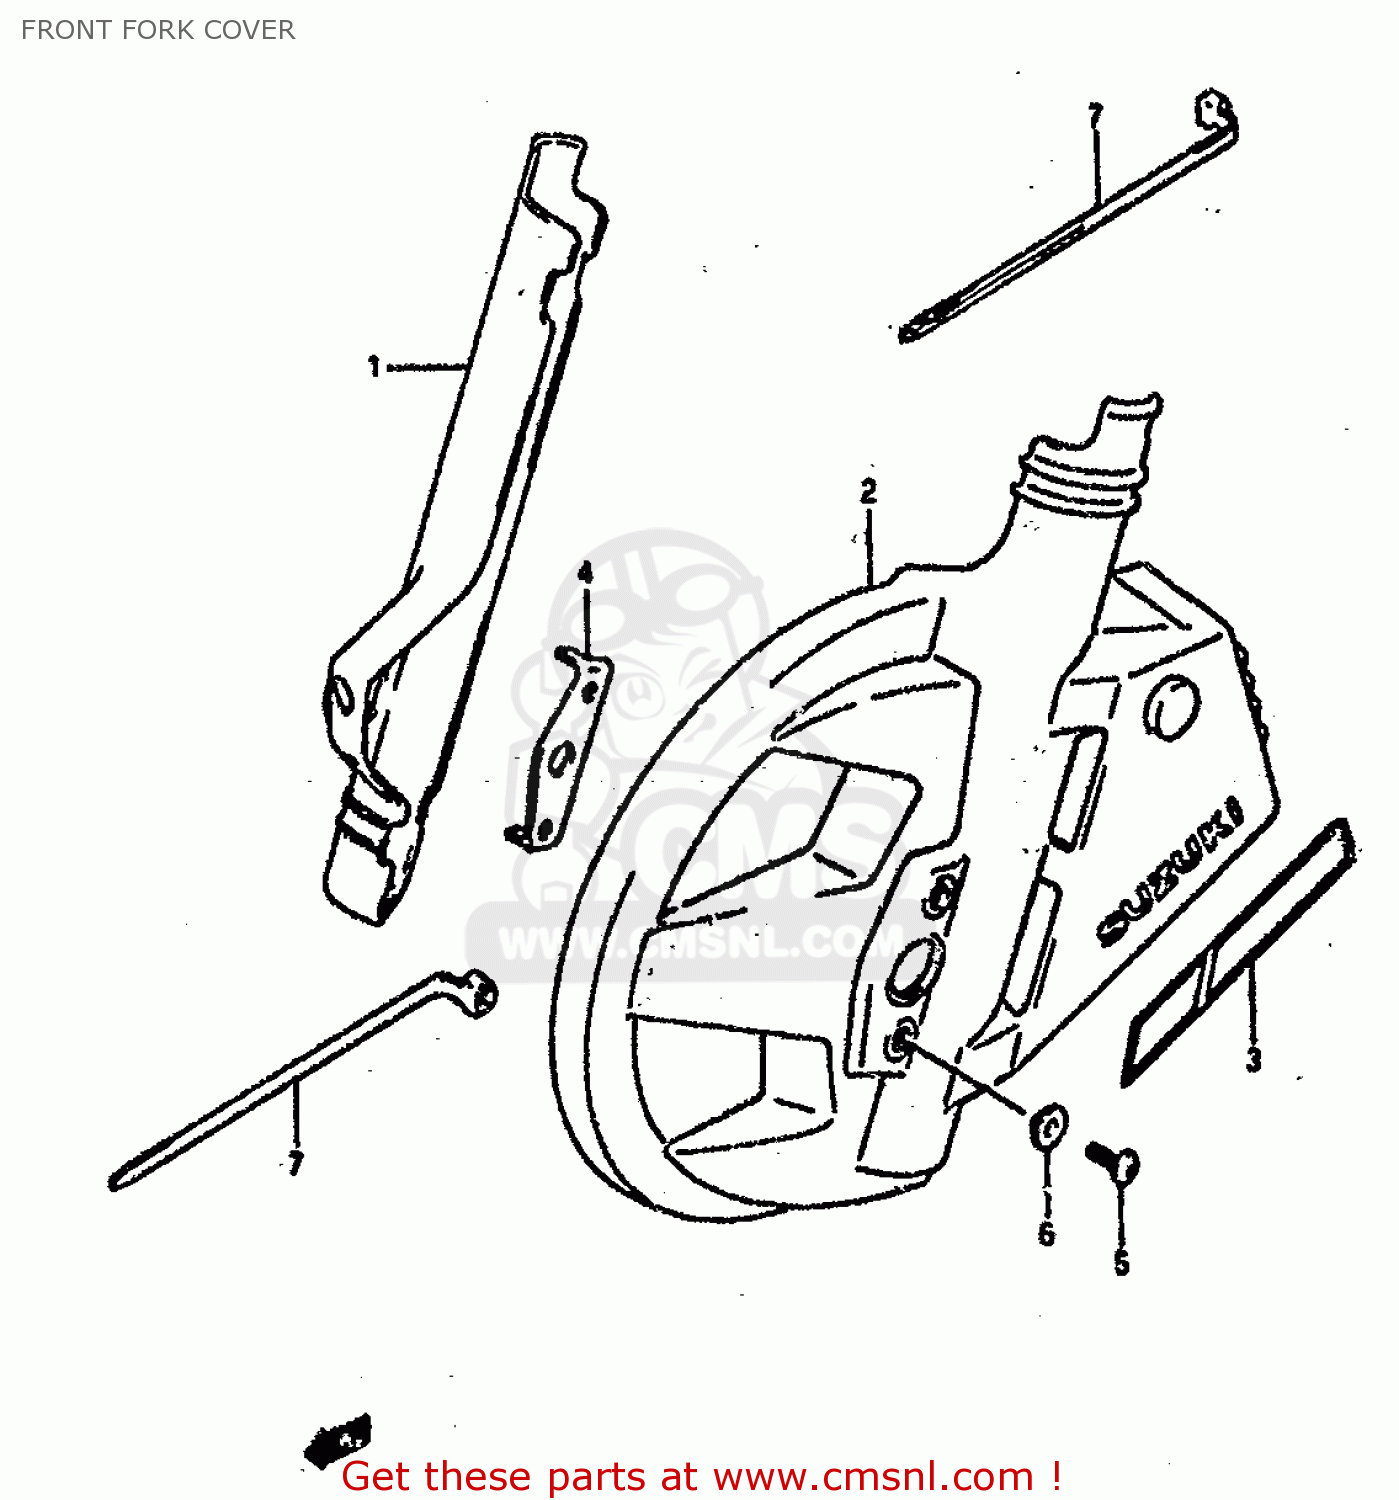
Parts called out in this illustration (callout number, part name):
1	PROTECTOR,FR FORK,R
2	PROTECTOR,FR FORK,L
3	TAPE,PROTECTOR LH
4	PLATE,PROTECTOR SET
5	SCREW 6X12
6	WASHER
7	CLAMP
